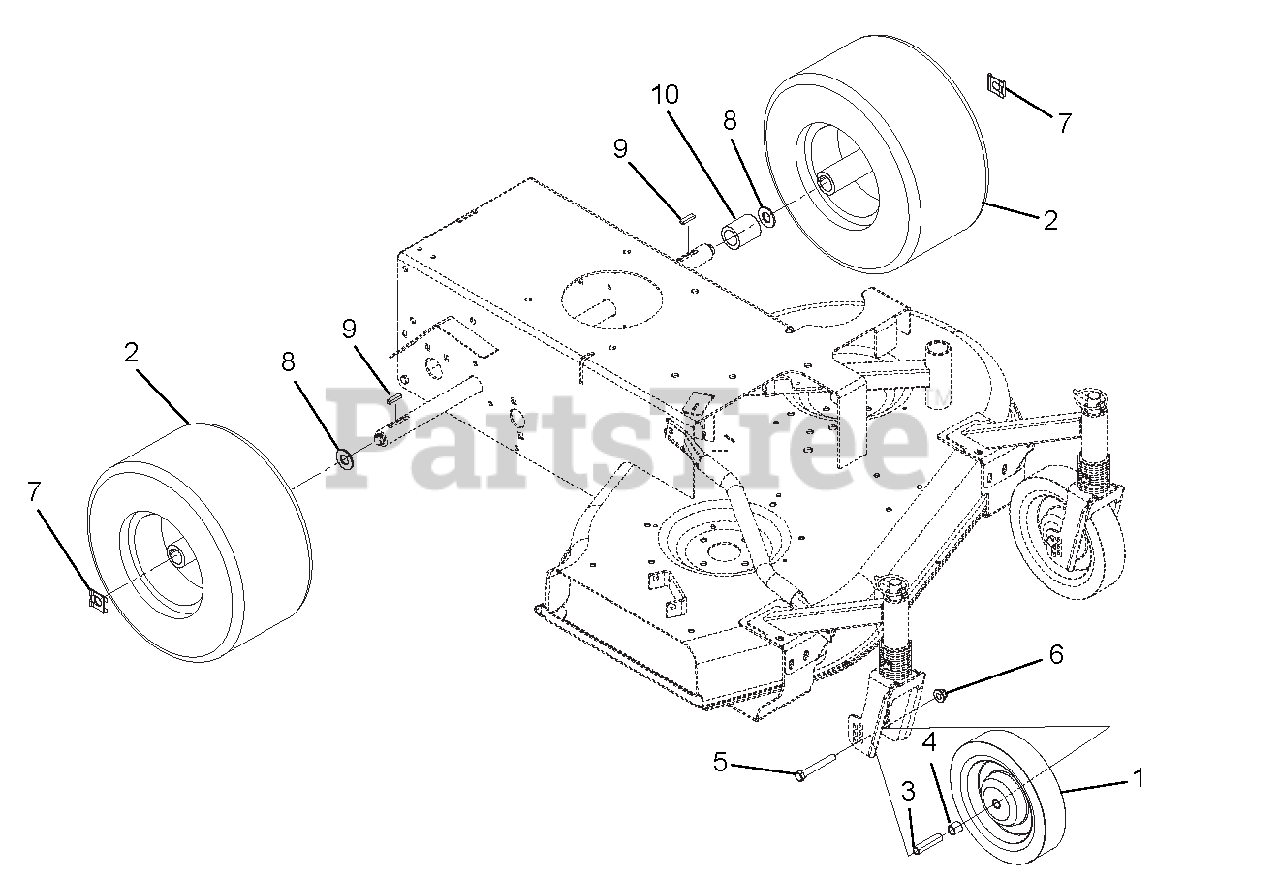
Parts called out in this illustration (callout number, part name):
1	WHEEL, 8.0X1.75X.50 - BALL BRG
2	ASSY, TIRE/WHEEL 6X13
3	SPCR, WHEEL .385X.500X2.00
4	SPACER-WHEEL
5	@BLT-HEX .38-16X2.75 GR5 YWZC
6	@NUT-LK-NYL-FLG .38-16 YWZC
7	CLIP, SNAP .625 DIA
8	@WSHR-FL-STL.656X1.31X.095 YWZ
9	KEY-RECT .25X.188X1.00
10	SPACER, 1.0X1.5X1.57
